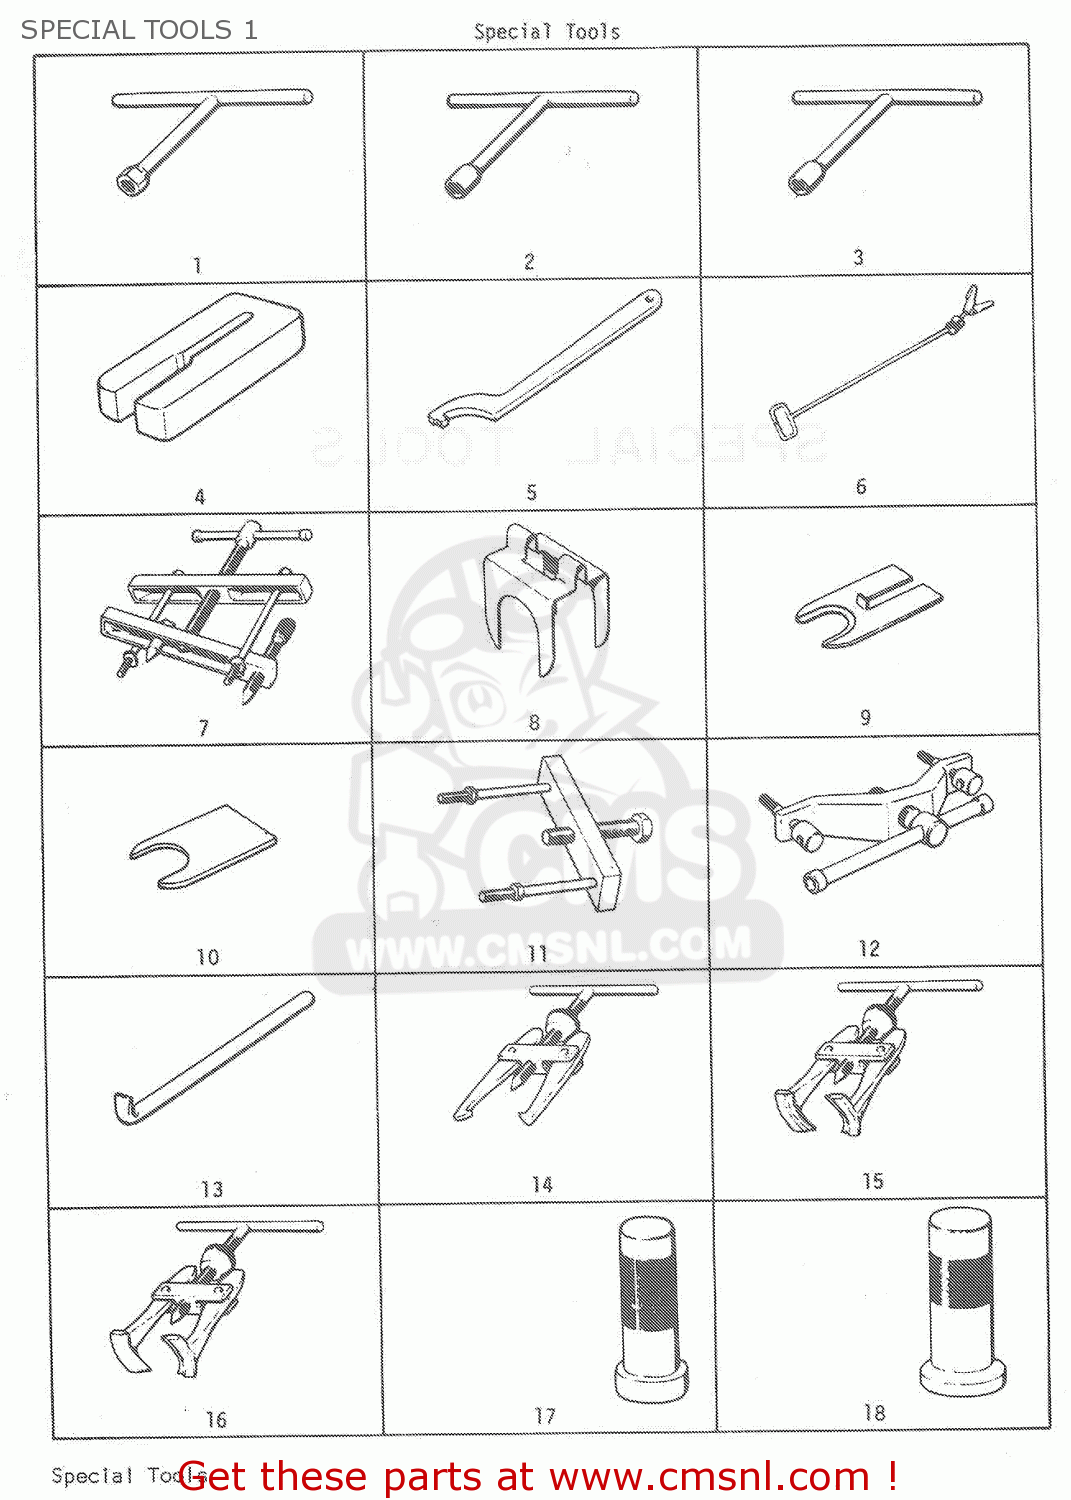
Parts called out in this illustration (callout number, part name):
1	TOOL
2	TOOL
4	PISTON HOLDER
5	UNIVERSAL CLAMP WRENCH
6	EXHAUST PIPE CL
7	CRANKCASE SEPARATING TOOL
13	OIL SEAL,REMOVER
14	BEARING,GEAR PULLER
17	BEARING & OIL SEAL INSTALLING TOOL
18	BRG INSTAL TOO
